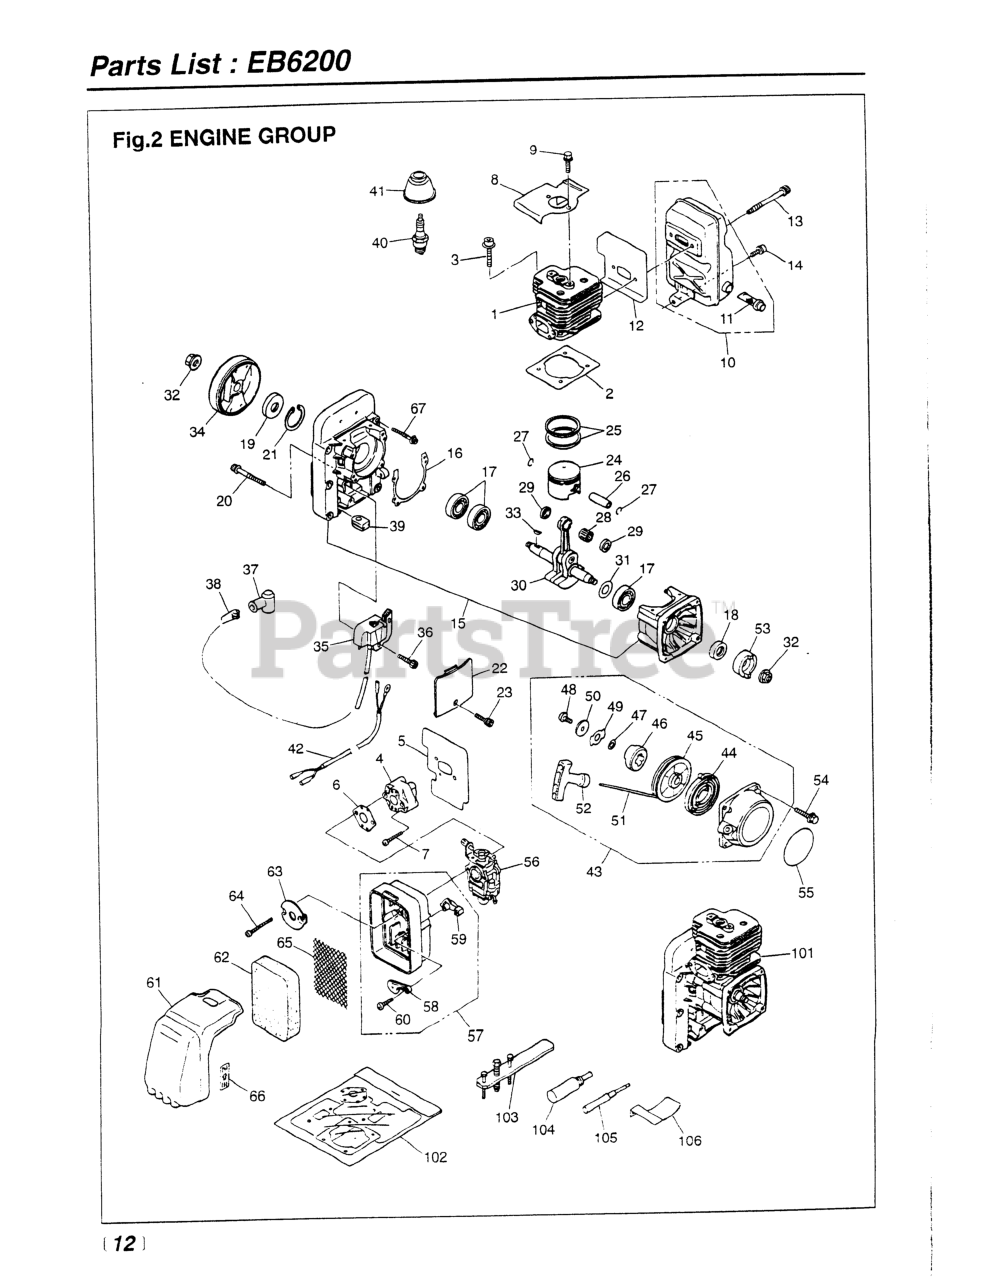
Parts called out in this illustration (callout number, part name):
2	GASKET, BASE
5	GASKET
6	GASKET, CARB (RPLS -13131)
7	SCREW, M5 x 35
8	COVER
9	BOLT, M5 x 10
11	ARRESTER
12	GASKET
13	BOLT, M6 X 70
14	BOLT, M6 X 12
15	CRANKCASE (USE 2750-21101)
16	GASKET
18	SEAL, OIL - STARTER SIDE
20	BOLT, M5 X 30
21	RING, SNAP, M35 X 1.5
22	COVER
23	BOLT, M4 X 16
24	PISTON
25	RING
26	PIN, PISTON
27	RING, SNAP
28	BEARING
29	WASHER (RPLS 1491-41510)
31	SHIM (REPLACES 848-870-G000)
32	NUT, M10
33	KEY
34	ROTOR (USE 2750-71111)
35	COIL ASSEMBLY, IGINITION
36	BOLT, M4 X 16
38	SPRING
39	GROMMET
41	CAP (NO LONGER AVAILABLE)
42	CORD COMP.
44	SPRING (RPLS -75220)
46	DOG
47	WASHER
48	SCREW
49	RETAINER (RPLS 1861-75161)
50	WASHER
51	ROPE
52	KNOB
53	PULLEY (RPLS -75210)
54	BOLT, M5 x 20
56	CARBURETOR (WYK-73-1)
58	PLATE
59	LEVER
60	SCREW (REPLACES 50030272)
62	ELEMENT (RPLS -82310)
63	PLATE (REPLACES -82511)
64	SCREW, M5 x 60
66	LABEL
67	BOLT, M6 X 40
102	KIT, GASKET
103	PULLER ASSY
104	STOPPER (TOOL) (RPLS 3320-9641
105	GUIDE (TOOL)
